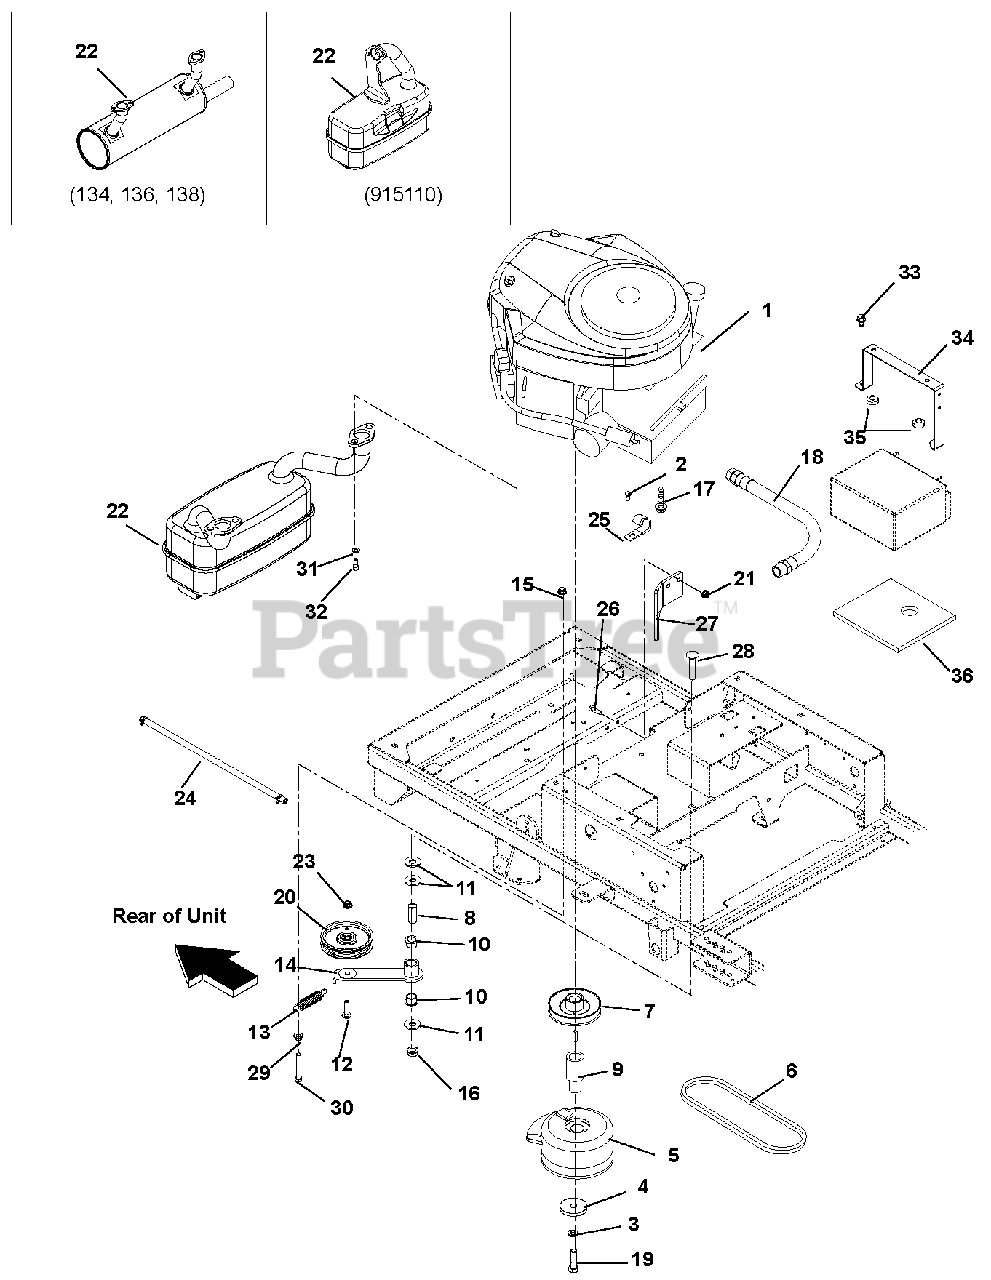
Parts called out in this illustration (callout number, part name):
1	Engine, 20 HP Kohler Twin SV710-0034 (915134)
2	Screw, Tapping .250-20 x .37 Hex Washer Head
3	Washer, Locking .44 x .109 Regular
4	Washer, Flat Steel .469 x 2.00 x .25
5	Clutch, ZTXL (915136, 138)
6	Belt, HA 62.50 Wrapped
7	Pulley-V 4.5X1.5 AB Section with Key
8	Bushing, Sleave .500 x .750 x .1.560
9	External, Crankshaft Lower
10	Bushing, Flange 0.75 x 0.875 x .625 x 1.125
11	Washer, Flat Steel .563 x 1.38 x .109
12	Bolt, Round Head Square Neck .38-16 x 1.50 Grade 5
13	Spring, Tension .105 x .812 x 3.88
14	Weldment, Ground Drive Idler Arm
15	Nut, 3/8-16 Flange Nyloc
16	Nut, Locking Top Flange .50-13
17	Screw, Tapping .38-16 x 1.00 Hex Washer Head
18	Hose Assembly, Oil Drive .38 x 11.5 OAL
19	Bolt, Hex .44-20 x 4.50 Grade 8
20	Assembly, 4" Idler
21	Nut, .31-18 Nyloc Flange
22	Muffler (915134, 136, 138)
23	Nut, Locking-Top-Flange .38-16
24	Assembly, Fuel Hose
26	Bolt, Hex .31-18 x 1.00 Grade 5
27	Clutch Stop
28	Bolt, Round Head Square Neck .50-13 x 2.50 Grade 5
29	Nut, Flange .375-16
30	Bolt, Hex .38-16 x 2.50 Grade 5
31	Washer, Locking .31 x .078 Regular (915134, 136, 138)
32	Screw, Cap .31-18 x .75 (915134, 136, 138)
33	Screw, Tapping .250-20 x .62 Hex Washer Head Thread
34	Strap, Battery
35	Button Bumper
36	Mat, Battery
